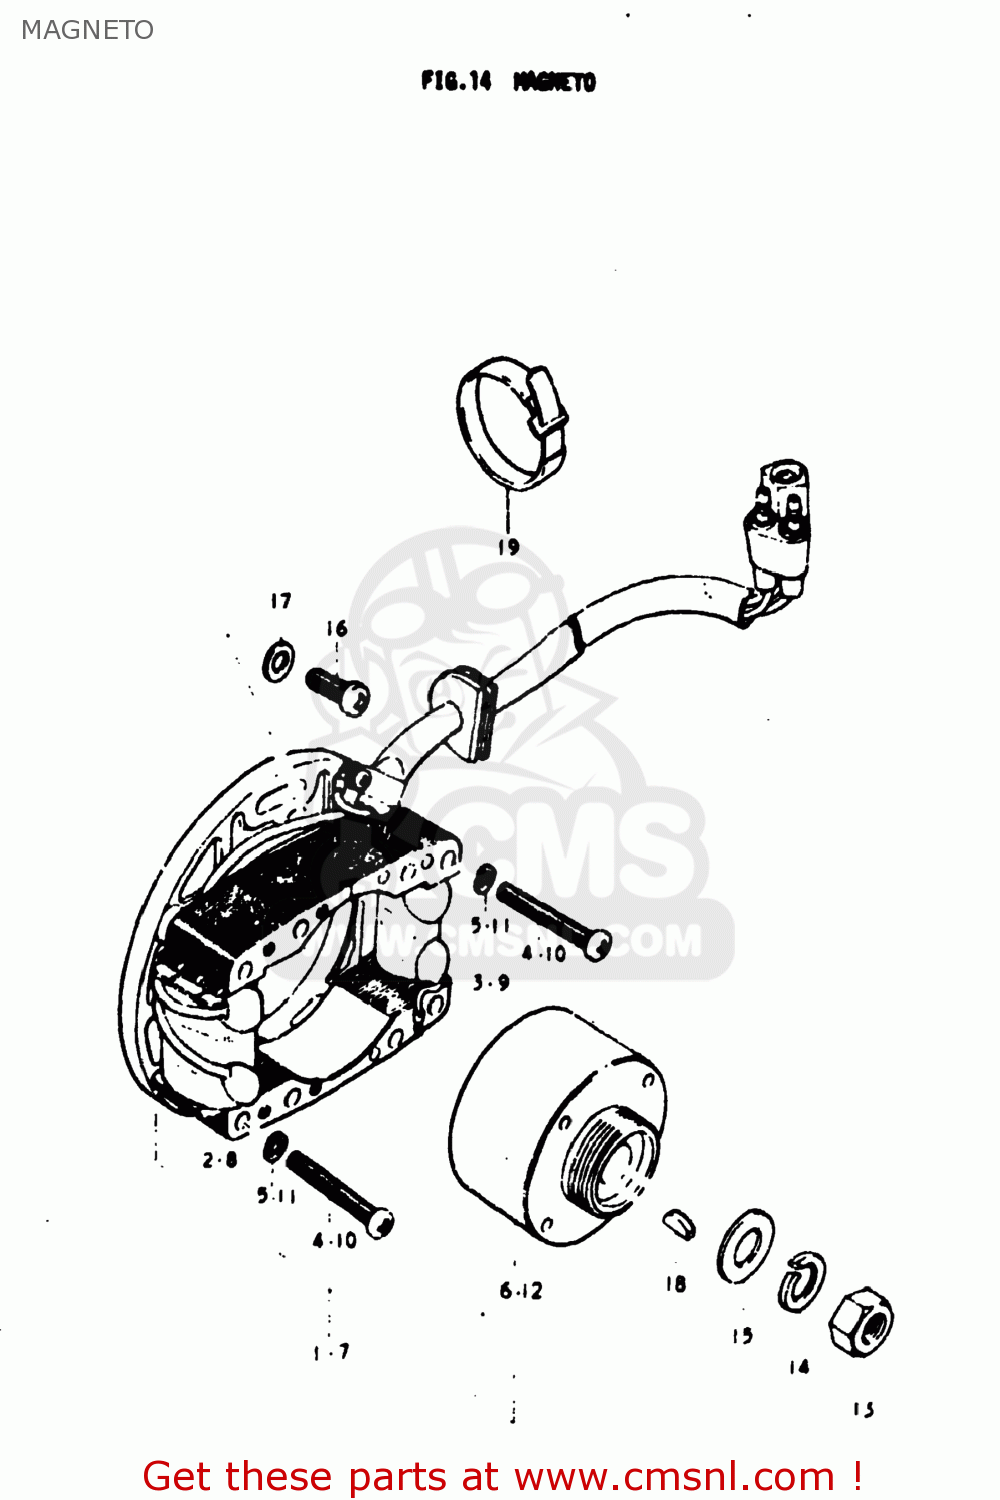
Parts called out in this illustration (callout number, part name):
1	MAGNETO ASSEMBLY
2	COIL
3	COIL,PULSER
4	SCREW
5	LOCK WASHER
6	ROTOR ASSEMBLY
7	MAGNETO ASSEMBLY
8	COIL
9	COIL,PULSER
10	SCREW
11	LOCK WASHER
12	ROTOR ASSEMBLY
13	NUT (10MM)
14	LOCK WASHER
15	WASHER
16	CROSS HEAD SCREW
17	WASHER
18	KEY
19	CLAMP
